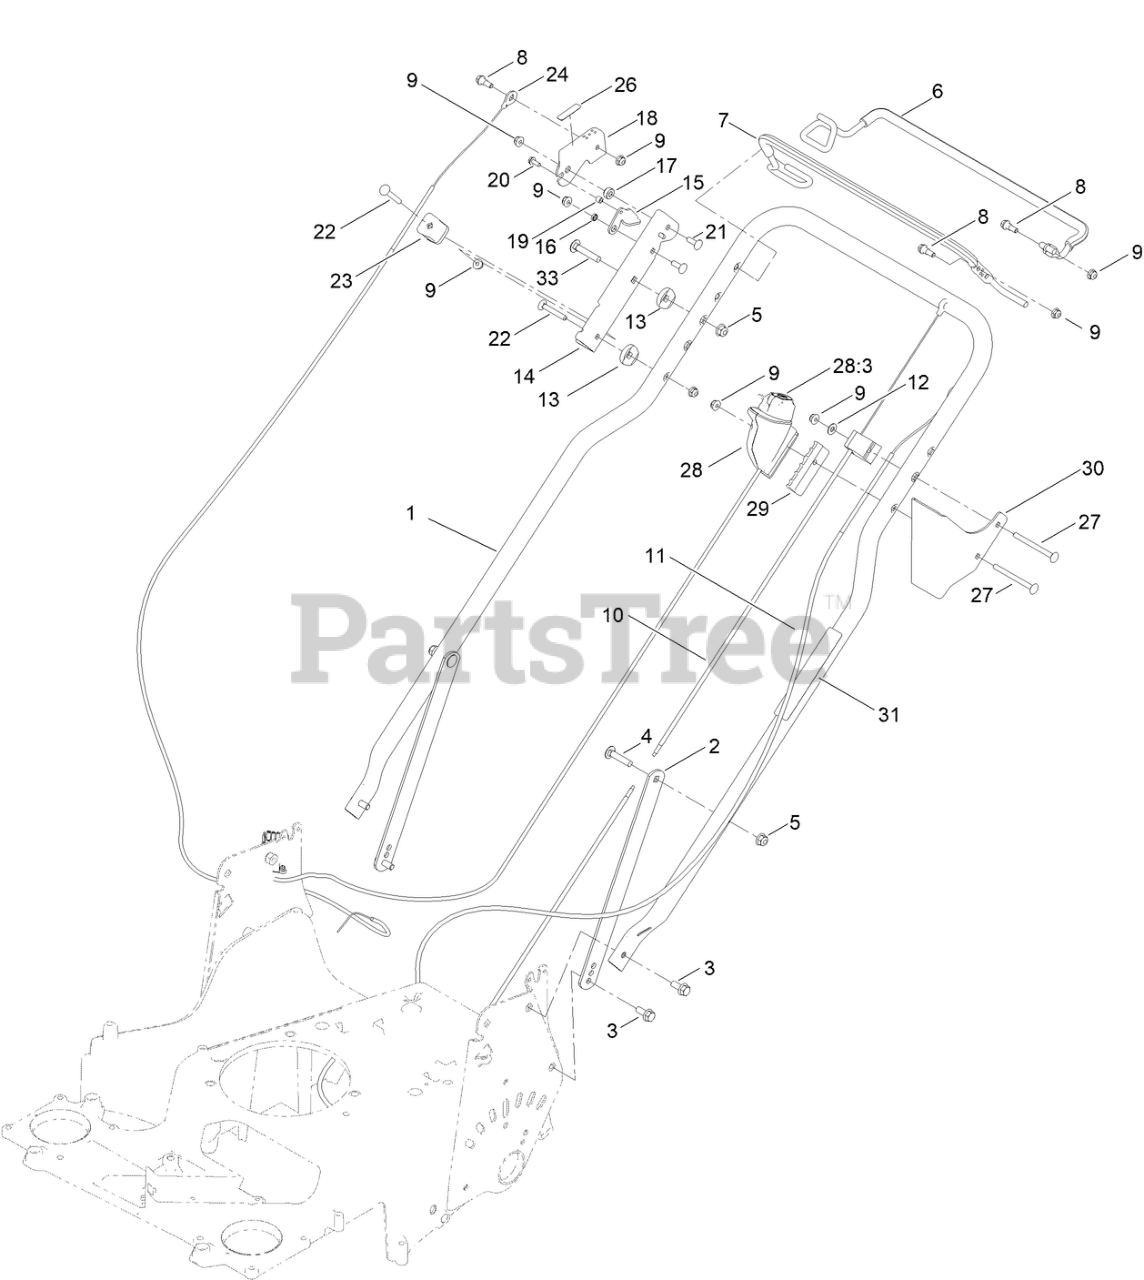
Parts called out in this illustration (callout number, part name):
2	SUPPORT-HANDLE
3	SCREW-HHF
4	BOLT-CARR
5	NUT-HF, NI
6	BAIL-TRACTION, COATED
7	BAIL-BBC, COATED
8	BOLT-SHOULDER
9	NUT-HF
10	CABLE-BRAKE
11	CABLE-TRACTION
12	WASHER-FLAT
13	WASHER-CURVED
14	MOUNT-LEVER, BRAKE
15	LINK-ACTUATION, BRAKE
16	SPACER
17	WASHER-STEPPED
18	LEVER-BRAKE
19	SPACER
20	SCREW-TAPTITE
21	BOLT-CARR
22	SCREW-CARR
23	ANCHOR-CABLE
24	CABLE-BRAKE, PARKING
26	DECAL-BRAKE, PARKING
27	SCREW-CARR,SPCL
28	SWITCH-STARTER ASM
28:3	STARTER BUTTON SERVICE ASM
29	SPACER-HOUSING, SWITCH
30	GUARD-SWITCH [BLACK]
31	DECAL-CONTROLS (60V START)
33	BOLT-CAR
